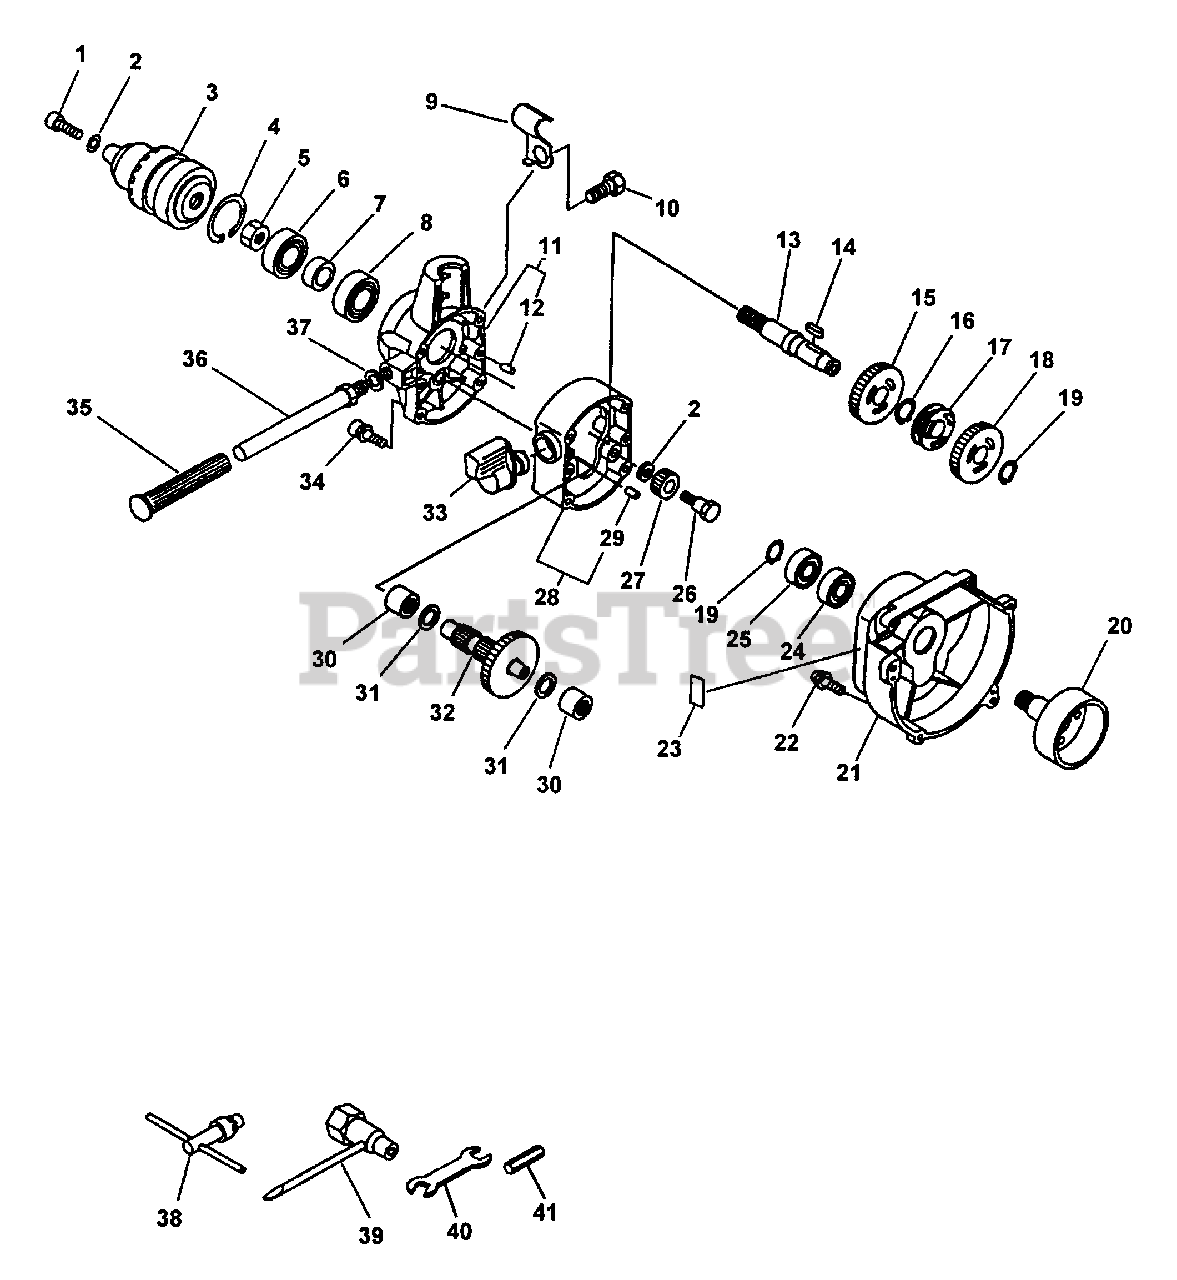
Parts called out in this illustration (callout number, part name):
1	SCREW - 6X20
2	WASHER - 6
4	RING, RETAINING - 32
5	NUT - 12
6	BEARING, BALL - 6002
8	BEARING, BALL - 6002
9	SPRING, FLAT
10	BOLT - 10X15
11	GEAR CASE ASSY
12	PIN - LOCATING
13	SHAFT, AXLE
14	KEY - 4X16
15	GEAR - SPUR
16	RING, RETAINING - 15
17	NAIL, CLUTCH
18	GEAR - SPUR
19	RING, RETAINING - 12
20	DRUM, CLUTCH
21	CASE, FAN
22	SCREW - 4X16
23	LABEL - HOT SURFACE
24	BEARING, BALL - 6001 DDU
25	BEARING, BALL - 6001C3
26	BOLT, CLUTCH
27	GEAR - SPUR
28	CASE, GEAR
29	PIN - LOCATING
30	BEARING, NEEDLE
32	GEAR - SHAFT
33	LEVER, CLUTCH
34	SCREW - 5X50
35	GRIP, HANDLE
36	HANDLE - FRONT
37	WASHER - 10
38	KEY, CHUCK
39	T-WRENCH - 10X19mm
40	SPANNER - 17X19mm
